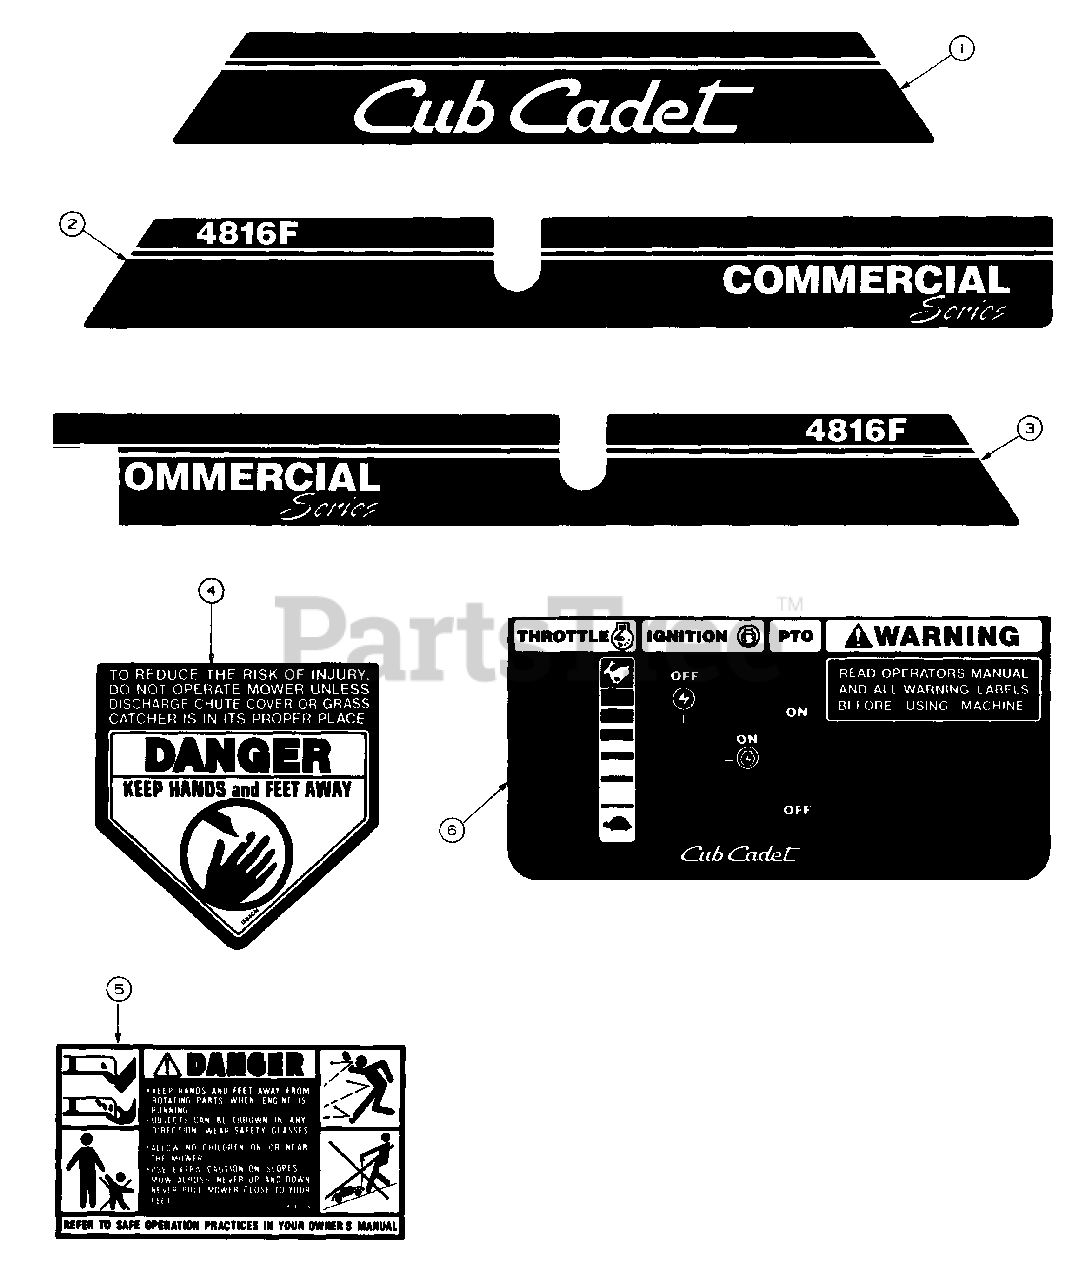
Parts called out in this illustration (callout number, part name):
1	Graphic, Belt Cover Front
2	Graphic 4816F, Belt Cover Right
3	Graphic 4816F, Belt Cover Left
4	Graphk, Danger Cut Finger
5	Graphic, Danger
6	Graphic, Control Panel
